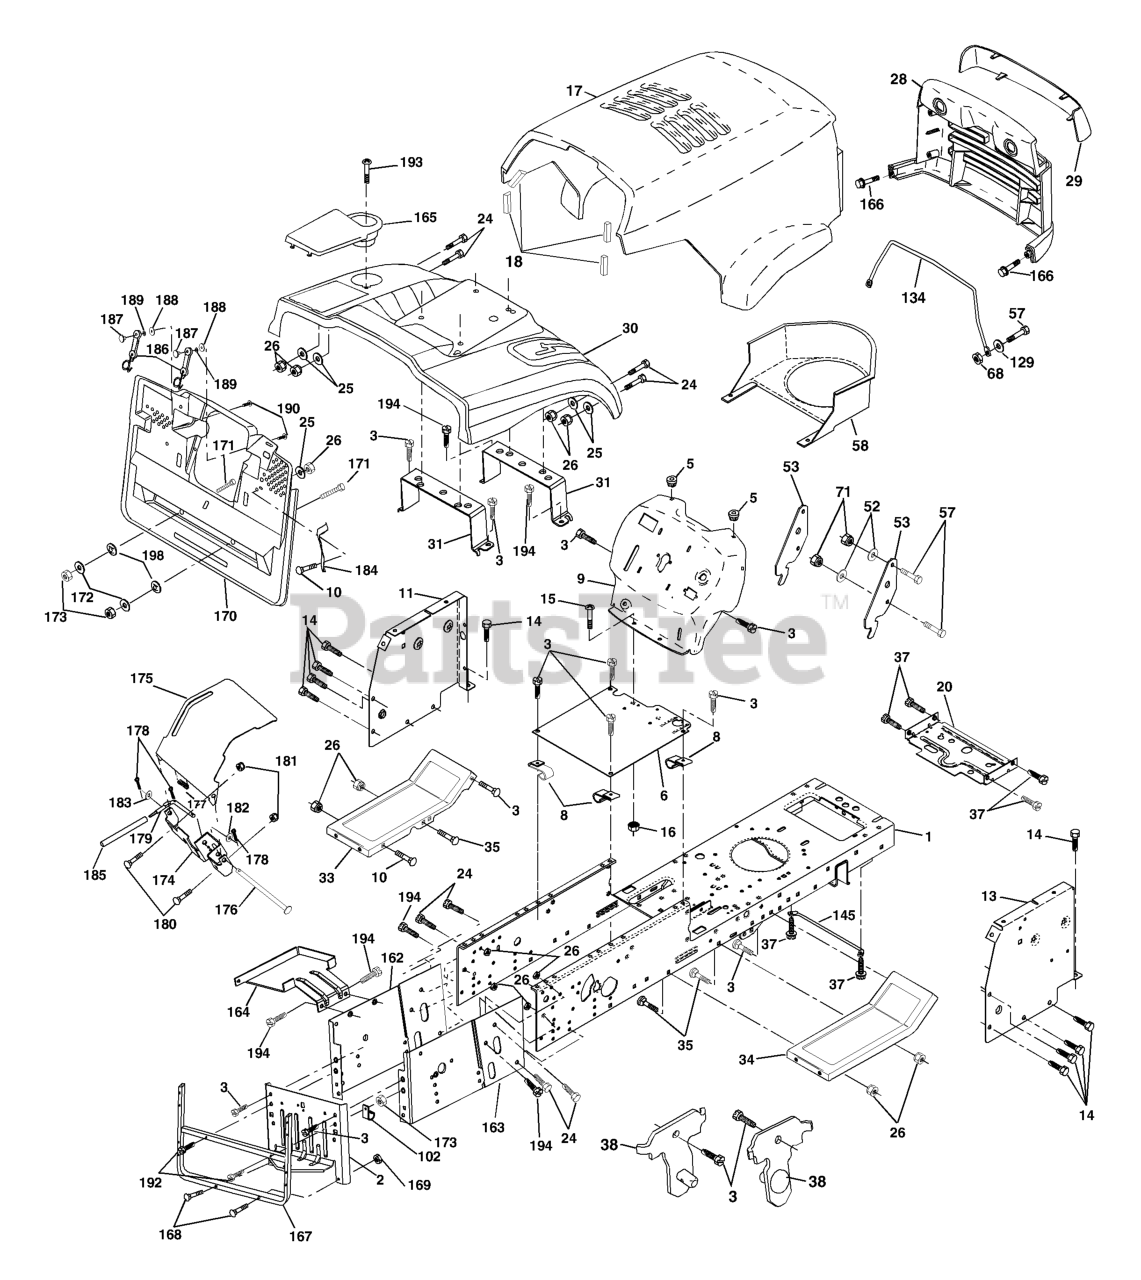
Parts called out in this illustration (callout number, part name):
1	CHASSIS STAMPING
3	SCREW 3/8-16X3/4
5	BUMPER.RUBBER.HOOD
6	SADDLE FLAT
8	CLIP,INSULATOR
10	BOLT D
11	PANEL DASH LH
13	PANEL DASH
14	SCREW LT
15	Screw, Machine, Truss Head 5/16-18 UNC x 3/4
16	NUT
17	HOOD
18	BUMPER HOOD T
20	PLATE MTG
24	BOLT
25	WASHER
26	NUT
28	GRILL
29	LENS
31	BRACKET SUPPORT FENDER
33	FOOT REST LH
34	FOOTREST RH
35	BOLT
37	Screw Thdrol 5/16-18 x 1/2 TYT
38	BRACKET
52	WASHER
53	BRACKET PNT PICK OFF LT/PL
57	BOLT
58	AIR DUCT P/L/LT
68	NUT
71	NUT.CROWNLOCK.1/4
102	CLIP T
129	WASHER
134	ROD SUPPORT HOOD LT/PL HUS.
145	ROD PIVOT CHASSIS/HOOD
165	COVER BATTERY
166	SCREW
167	SUPPORT.ASM.BACKPLATE
168	BOLT.ROUND.HEAD.SQUARE.NECK
169	NUT T
170	COVER BACKPLATE
171	BOLT
172	WASHER
176	HINGE PIN
177	SPRING COVER LH
178	COTTER PIN
180	BOLT RB
181	LOCKNUT
183	WASHER
185	TUBE LEVER
186	LATCH ASSY
187	WELDNUT
189	LOCKWASHER #10
190	SCREW
192	SCREW LT
193	Screw Truss 1/4-20 x 3/4 Tap/R
194	SCREW 3/8-16X3/4
